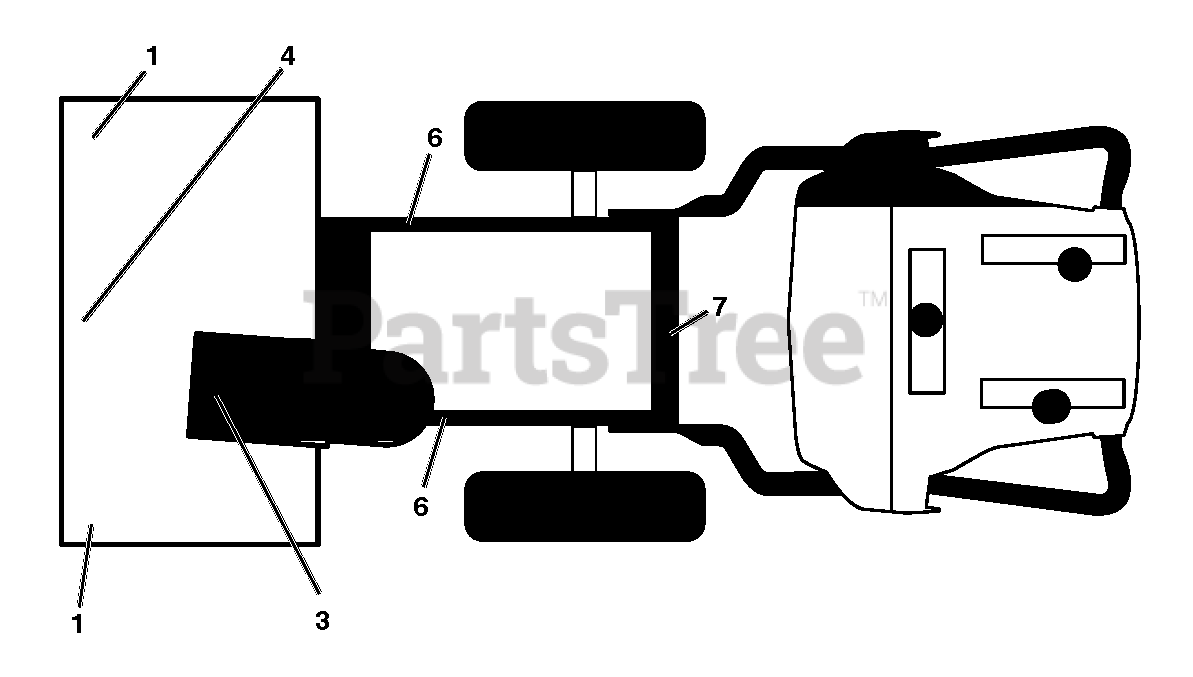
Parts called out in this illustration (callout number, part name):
1	DECAL.AUGER.SAFETY.
3	DECAL.CHUTE.SAFETY.EU/SC.17
4	DECAL.AUGER."
6	DECAL.BELT.GUARD.
7	DECAL.NOISE.LEV.105/CE.EAC.UKR
